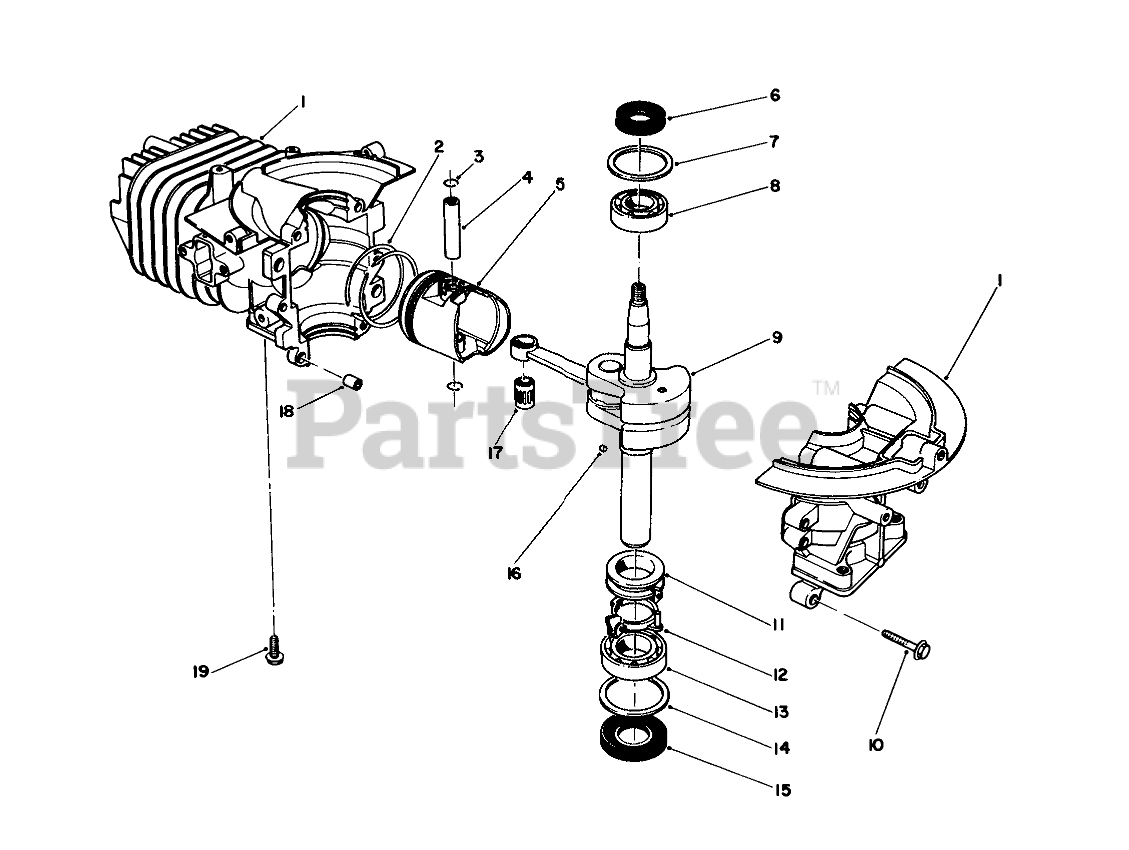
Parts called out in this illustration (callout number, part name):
1	CYLINDER/CRANKCASE
2	RING SET
4	HOUSING - CYL AIR, LH
5	Piston
6	OIL SEAL
7	WASHER-UPPER
8	BEARING-UPPER
9	CRANKSHAFT
11	SPACER
12	BRACKET
13	LOWER BRG
14	WASHER-LOWER
15	SEAL-OIL
17	BEARING
